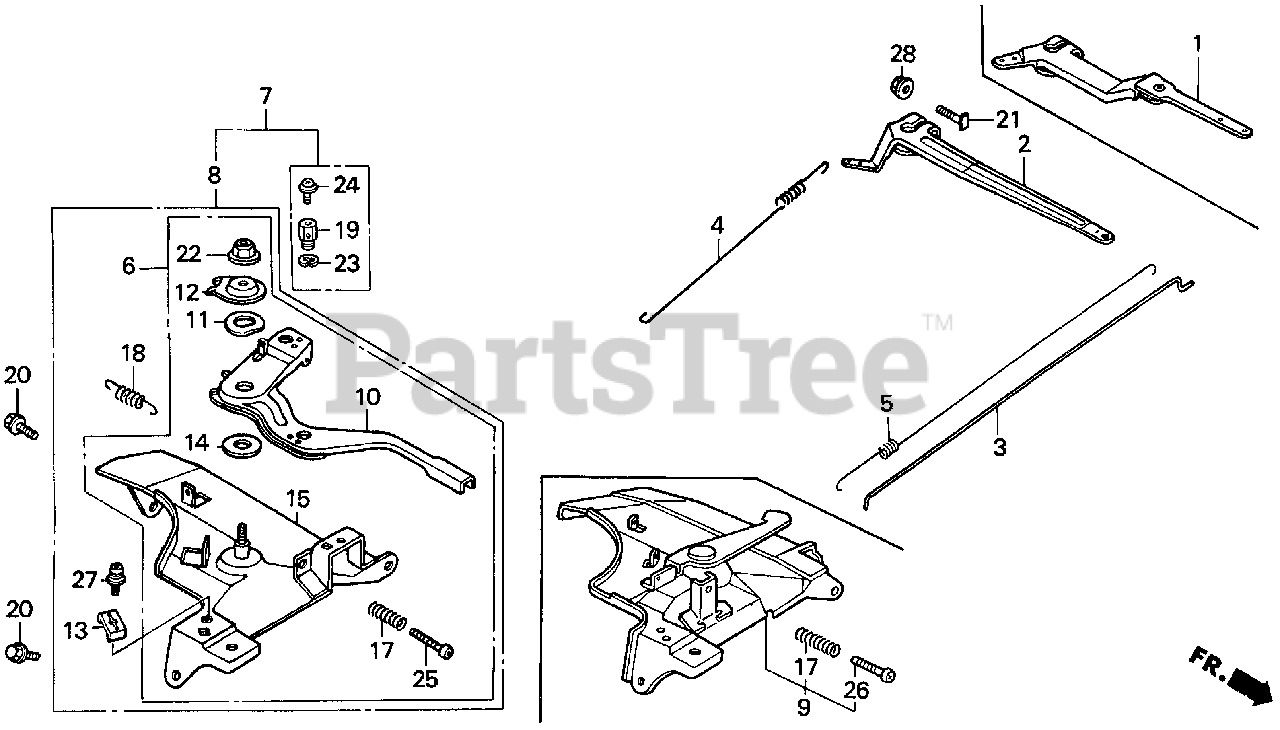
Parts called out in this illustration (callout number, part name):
2	ARM, GOVERNOR
3	ROD, GOVERNOR (STD)
3	ROD, GOVERNOR
4	SPRING, GOVERNOR
5	SPRING, THROTTLE RETURN
7	CONTROL ASSY. (REMOTE)
10	LEVER, CONTROL
11	SPRING, LEVER
12	WASHER, CONTROL LEVER
13	HOLDER, CABLE
14	SPACER, CONTROL LEVER
15	BASE, CONTROL
17	SPRING, CONTROL ADJUSTING
18	SPRING, CABLE RETURN
19	HOLDER, WIRE
20	BOLT, FLANGE (6X12) (CT200)
21	BOLT, GOVERNOR ARM
22	NUT, SELF-LOCK (6MM)
23	CIRCLIP (5MM)
24	SCREW, PAN (4X6)
25	SCREW, PAN (5X32)
27	SCREW, PAN (5X16)
27	SCREW-WASHER (5X16)
28	NUT, FLANGE (6MM)
